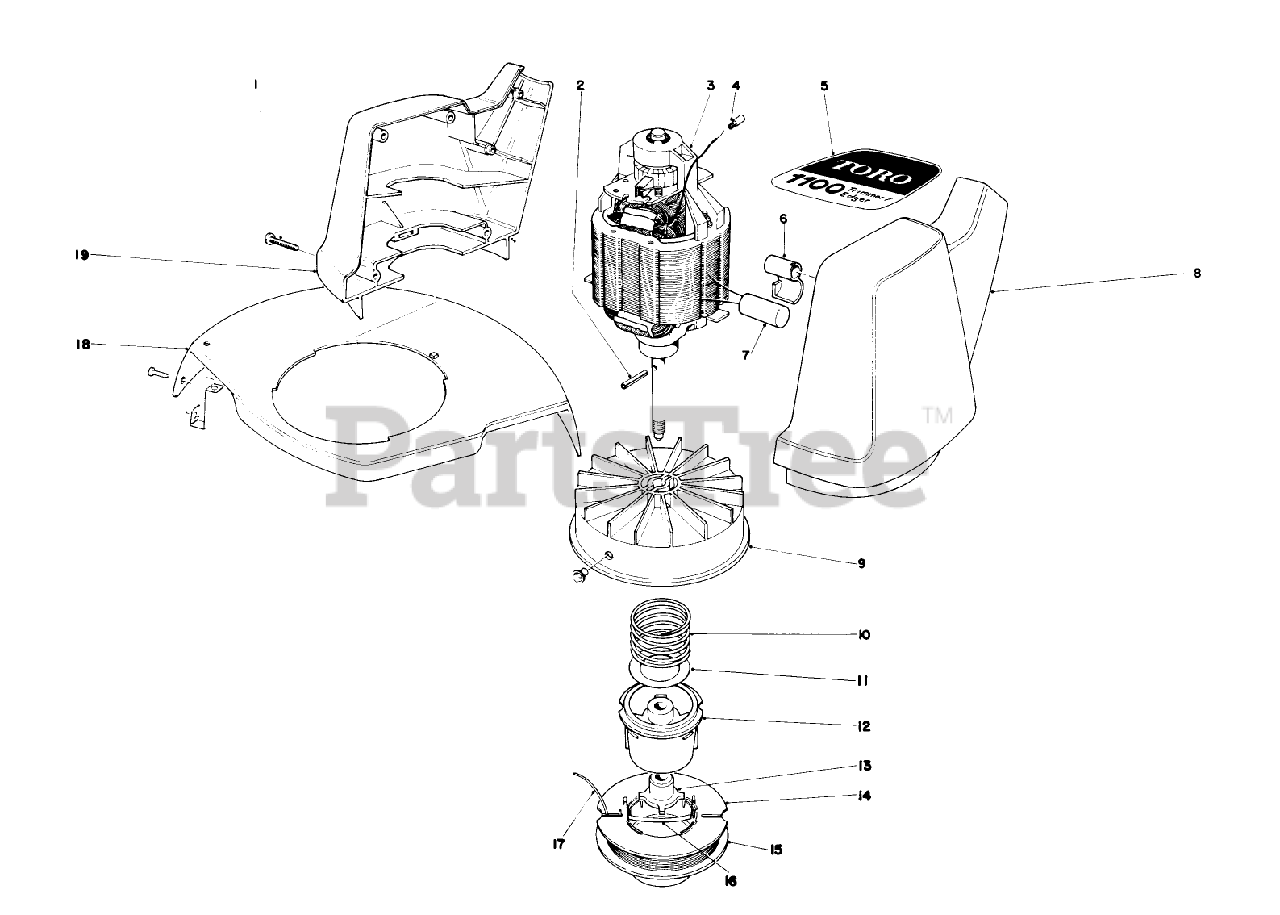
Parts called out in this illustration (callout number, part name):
1	SCREW-PPH
2	COIL PIN
3	Motor
4	CONNECTOR WIRE JOINT
5	DECAL - TORO 1100
6	Clamp-Suppressor
7	Suppressor
8	Left Motor Housing
9	DRUM W/EYELET
10	SPRING COMPRESSION
11	WASHER-FLAT
12	SPOOL CORE
13	Driver
14	Empty SPooI
15	Prewound Spool
16	SADDLE-SPOOL CAP
17	50-Coil.065" Cutting Line
18	Shield with Cut Off Blade
19	Right Motor Housing
